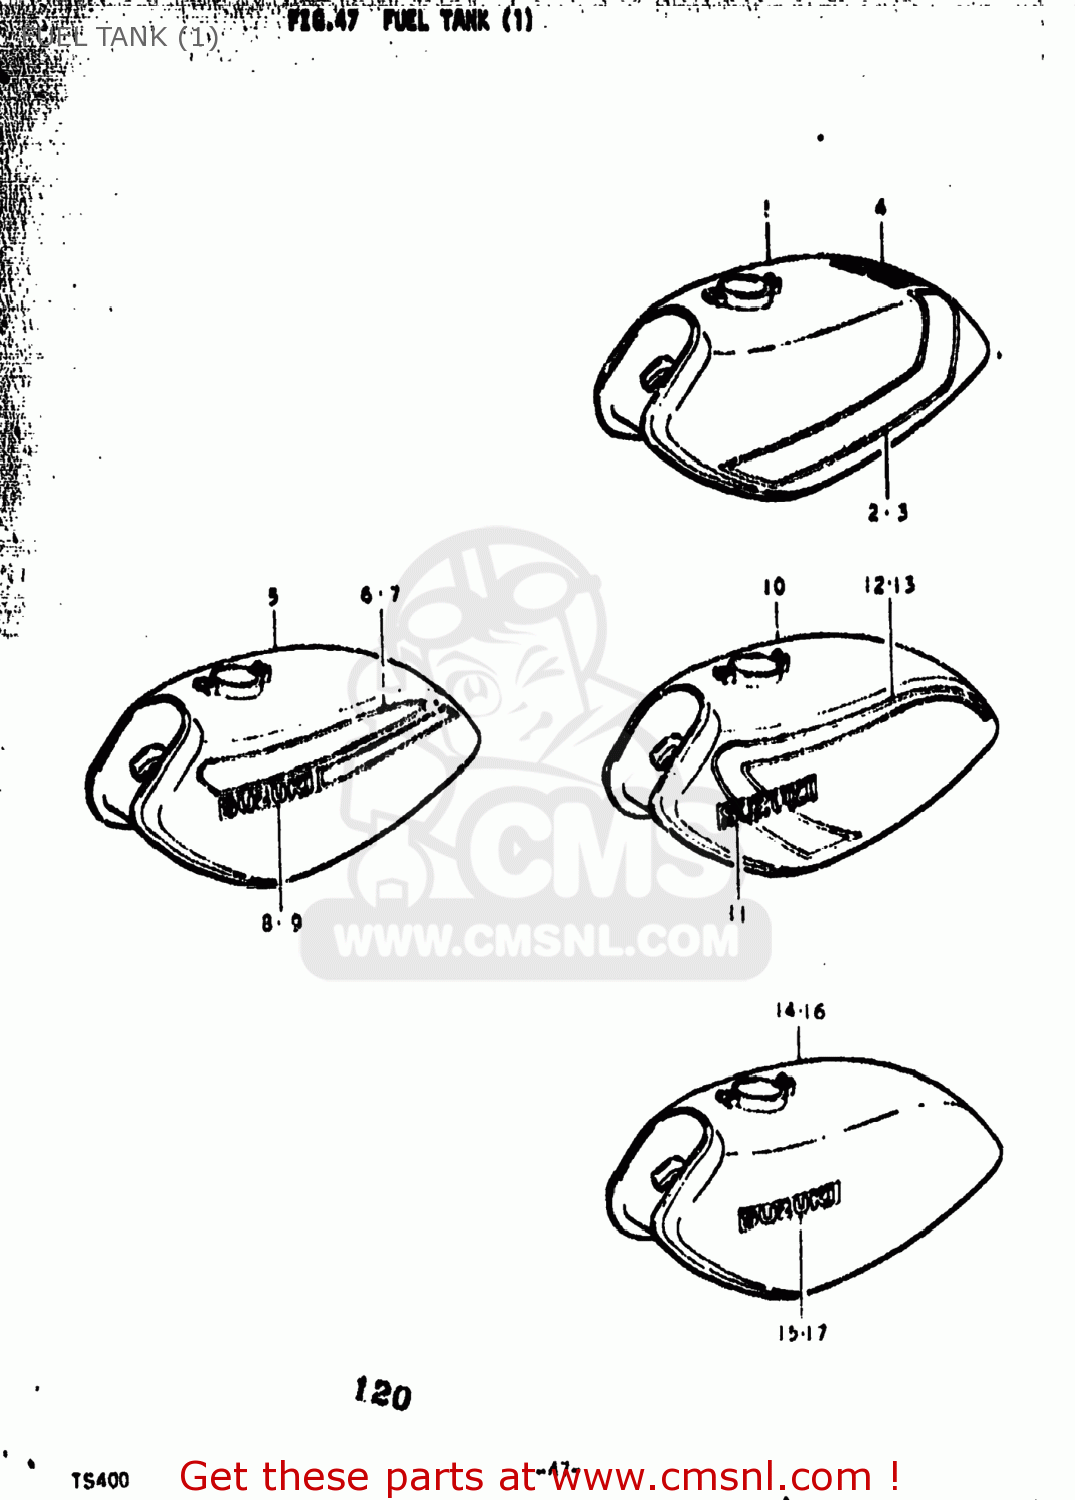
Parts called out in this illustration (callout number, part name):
1	TANK ASSEMBLY,FUEL
2	TAPE,FUEL TANK
3	TAPE,FUEL TANK
5	TANK ASSEMBLY,FUEL
6	TAPE,FUEL TANK
7	TAPE,FUEL TANK
8	EMBLEM
9	EMBLEM,FUEL TANK
10	TANK ASSEMBLY,FUEL
11	EMBLEM
12	TAPE,FUEL TANK
13	TAPE,FUEL TANK
14	TANK ASSEMBLY,FUEL
15	EMBLEM,FUEL TANK
16	TANK ASSEMBLY,FUEL
17	EMBLEM
